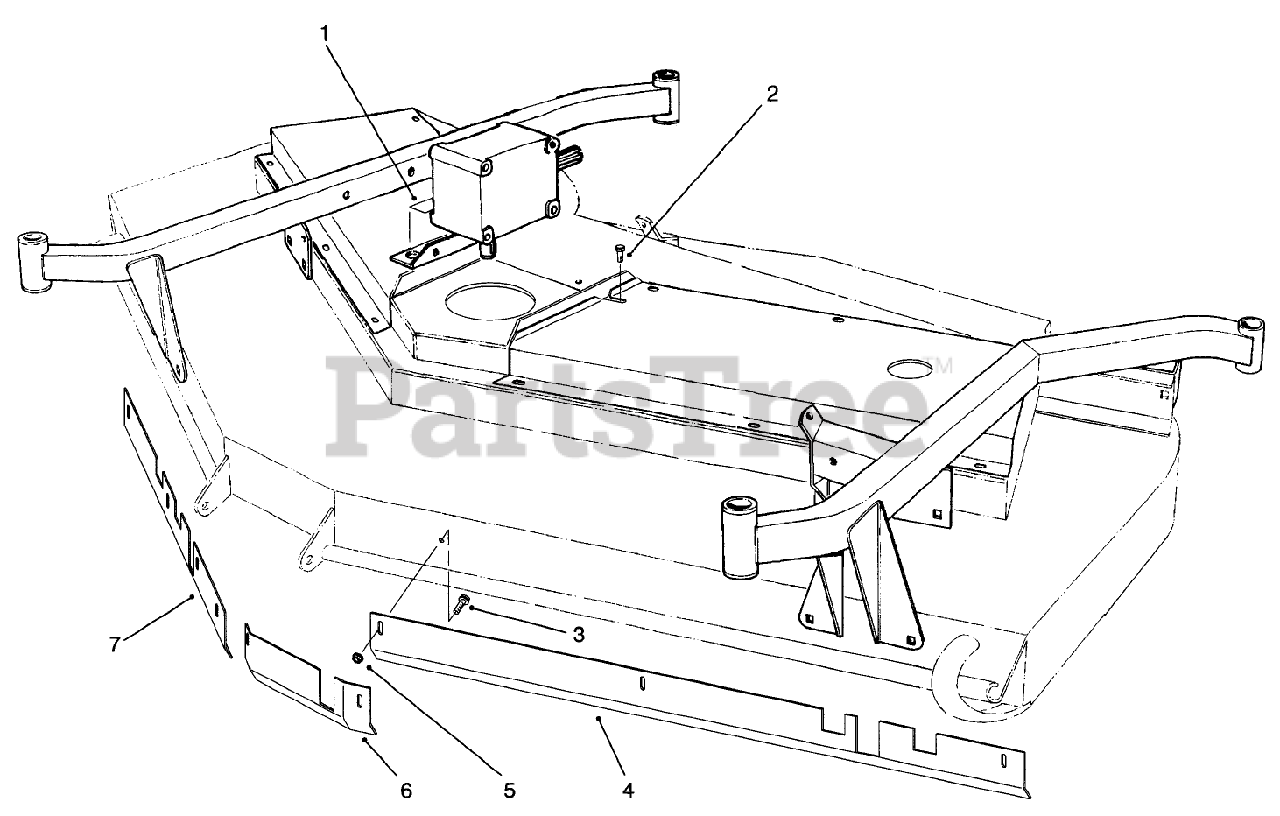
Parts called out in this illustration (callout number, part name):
1	DECAL-LUBE
2	SCREW-HH
3	SCREW-HHF
4	Baffle-LH
5	NUT-HF
6	Baffle-Center
7	Baffle-RH
